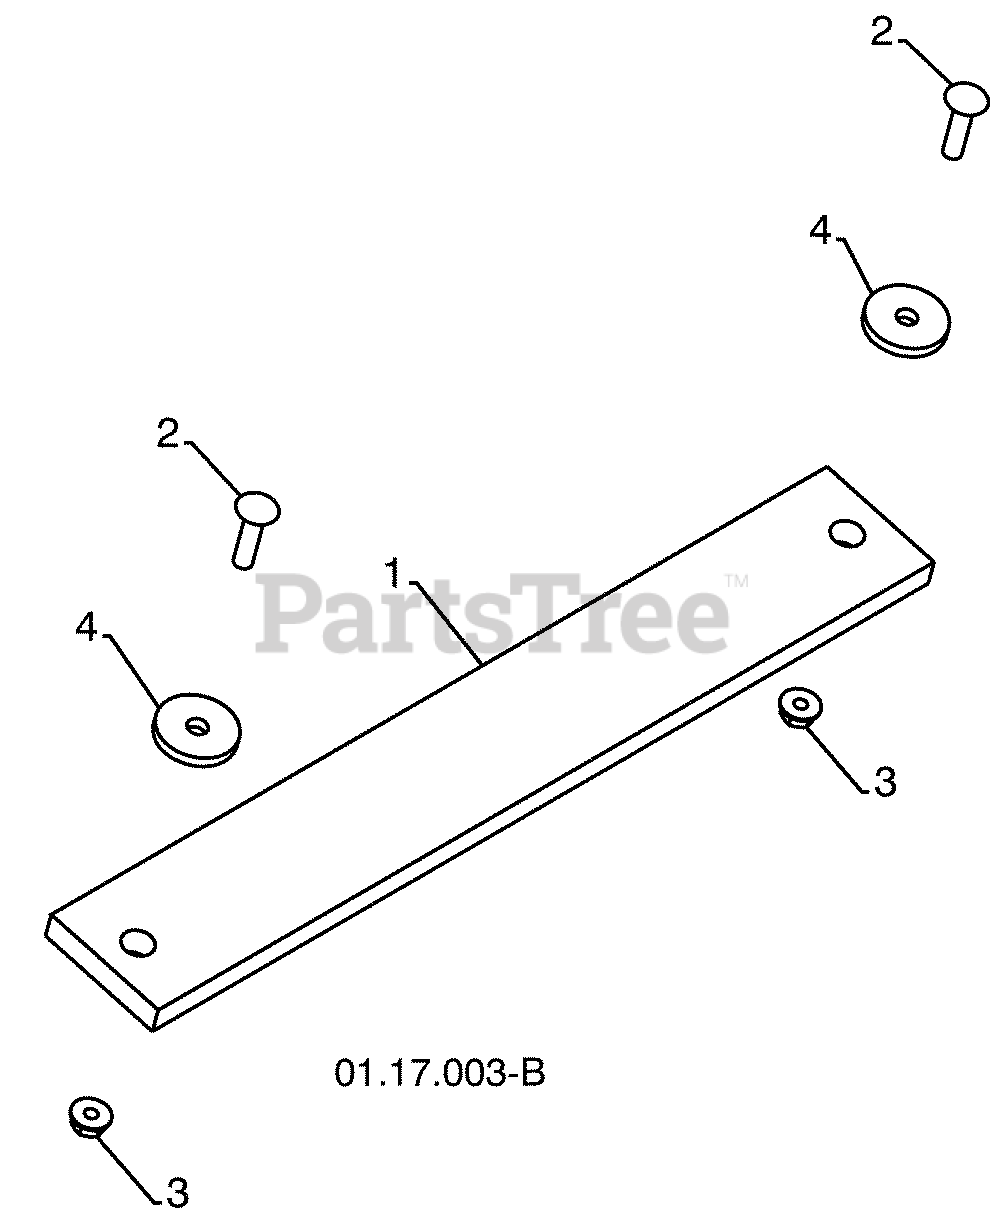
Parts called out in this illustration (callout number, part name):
1	WEIGHT BAR
2	CARRIAGE BOLT 5/16-18 X 1.25
3	NUT 5/16-18
